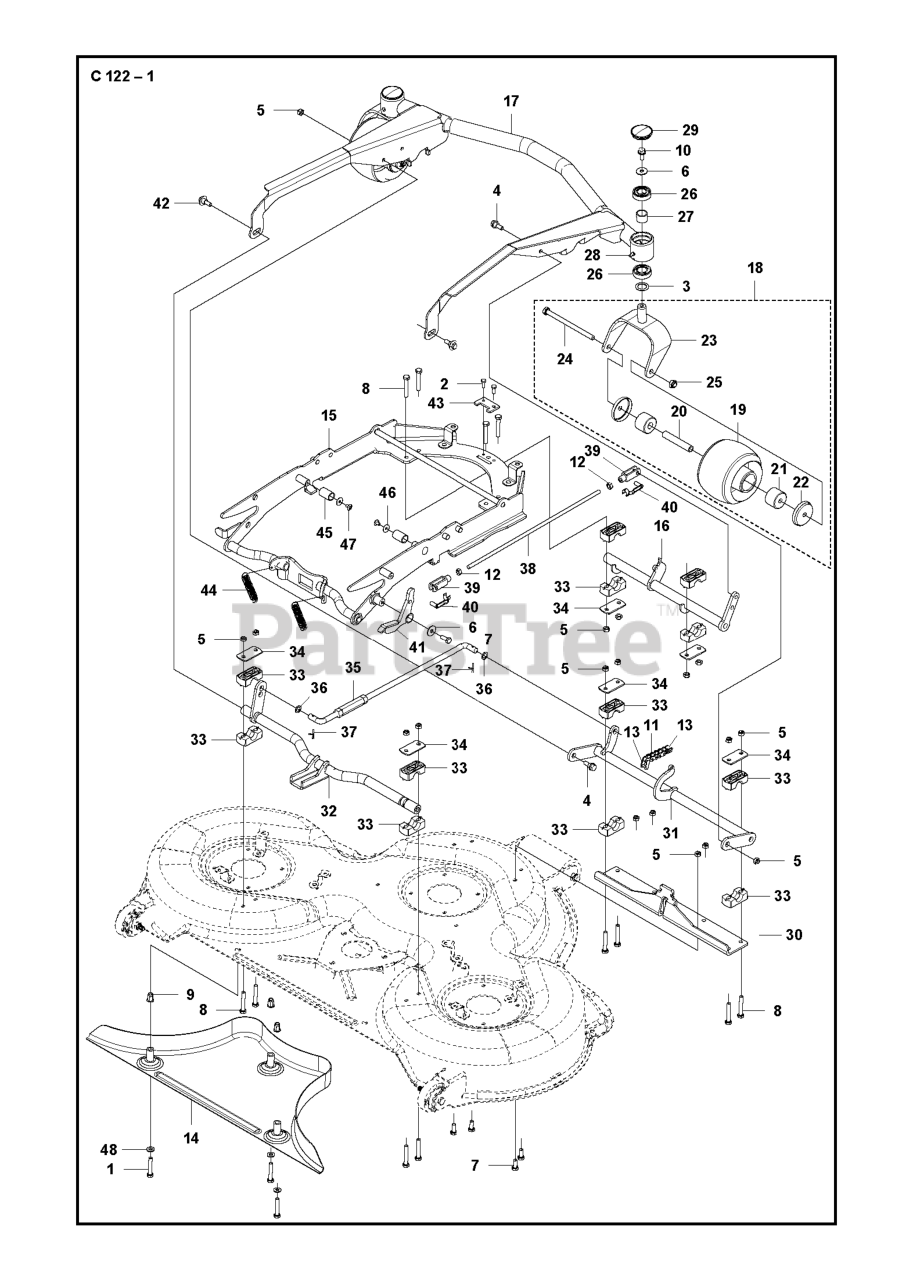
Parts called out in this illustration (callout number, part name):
1	SCREW
2	SCREW
5	LOCKNUT M8
12	NUT
18	PIVOT WHEEL ASSY BEARING SLEEV
25	NUT
28	GREASE NIPPLE
42	COLLAR SCREW
46	WASHER 19X6X1
48	WASHER BRB 8.4X17
